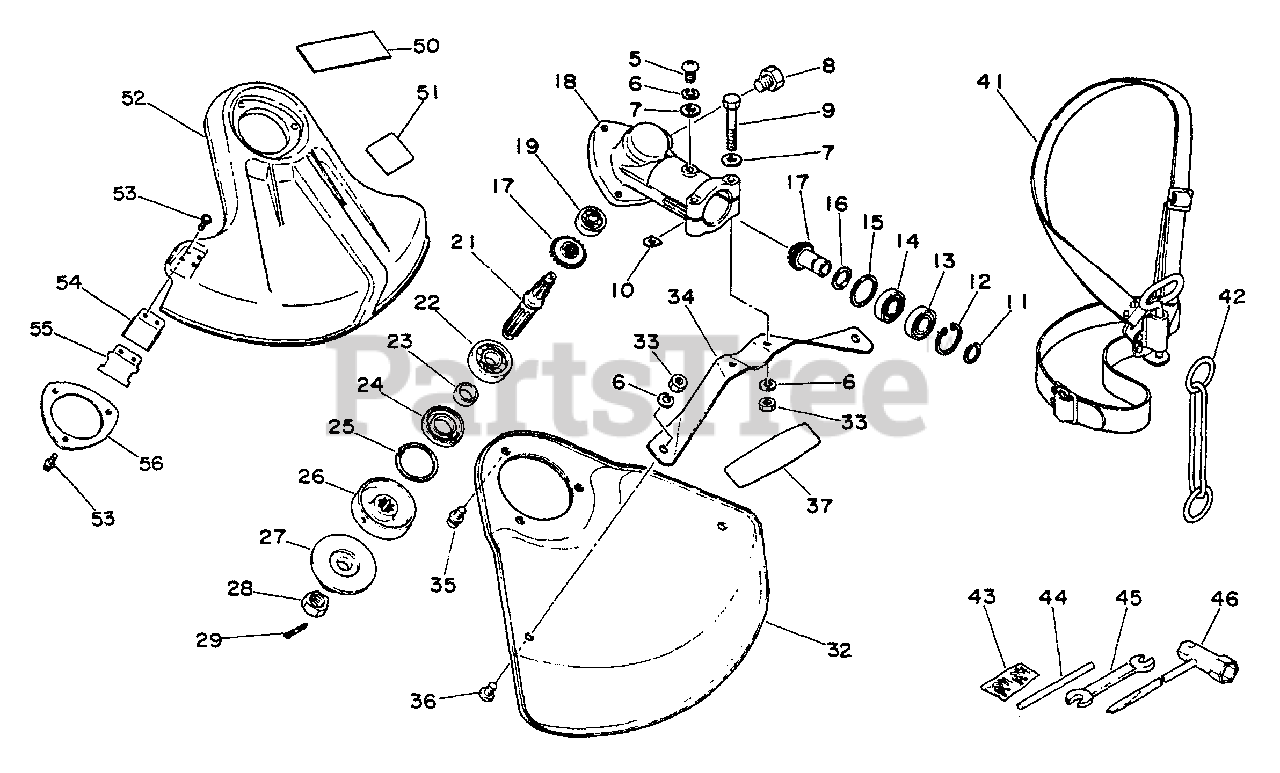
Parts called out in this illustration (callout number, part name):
5	SCREW - 5X10
6	LOCKWASHER - 5
7	WASHER - 5
8	BOLT - 8X8
9	BOLT - 5X35
11	RING, RETAINING
12	RING, RETAINING - 22
13	BEARING, BALL - 6900Z
14	BEARING, BALL - 6900
17	GEAR SET
18	CASE, GEAR
19	BEARING, BALL - 626
21	GEAR - SHAFT
22	BEARING, BALL - 6000
24	SEAL, OIL
25	RING, RETAINING - 25
26	ADAPTOR, BLADE - UPPER
27	ADAPTOR, BLADE - LOWER
28	NUT - 10 -- LEFT HAND
29	PIN, SPLIT - 2X22
32	SHIELD, DEBRIS - METAL
34	BRACKET, SHIELD
35	SCREW - 5X10
36	SCREW - 5X8
37	LABEL - ECHO
41	SHOULDER STRAP ASSY
43	PIN, SPLIT - 2X22
44	LOCKING TOOL
45	SPANNER - 8X10mm
46	T-WRENCH - 17X19mm
50	LABEL - ECHO
52	SHIELD, DEBRIS - PLASTIC
53	KNIFE, TRIMMER LINE
54	GUARD
55	SCREW - 5X16
56	PLATE, SHIELD
